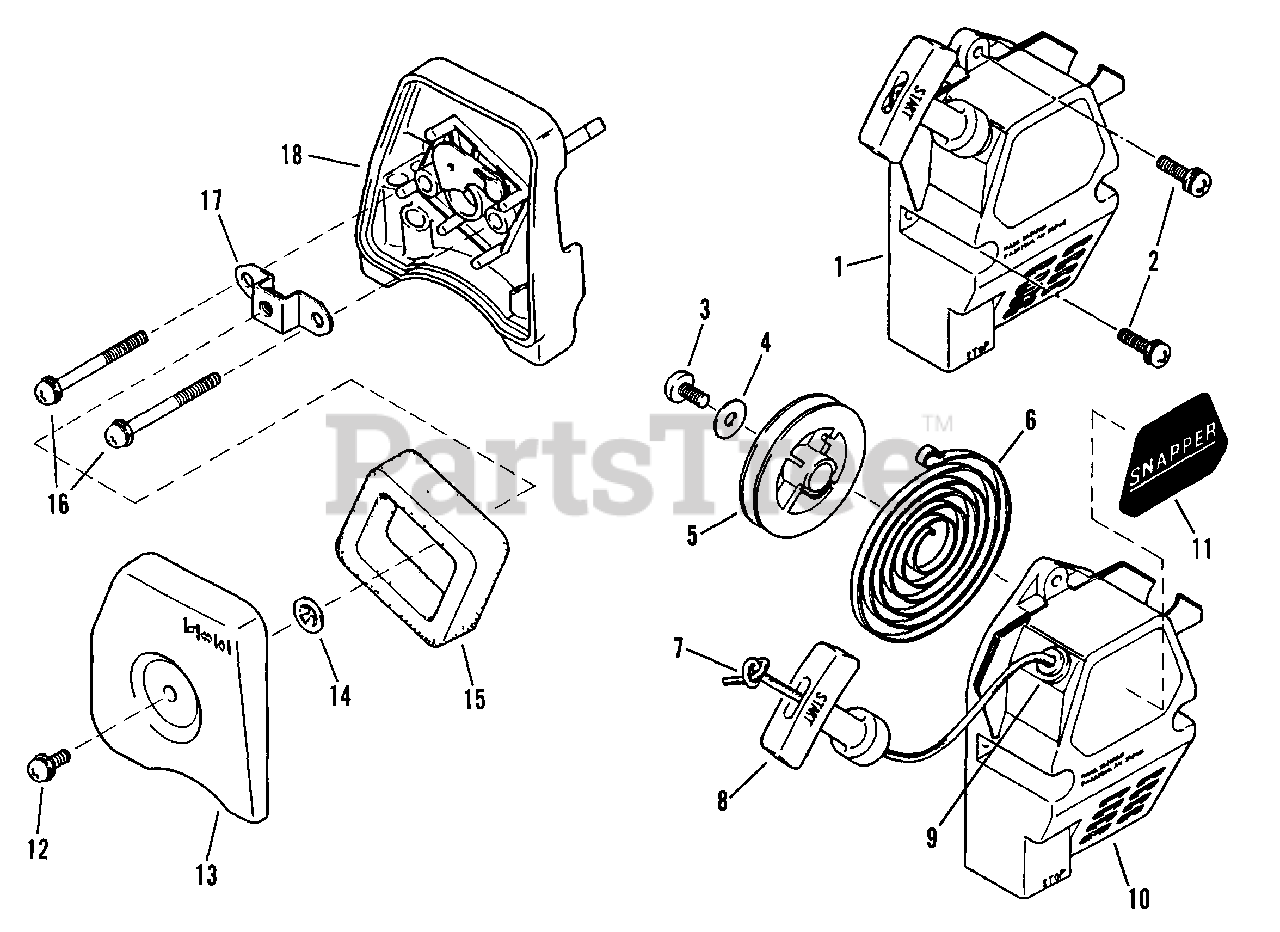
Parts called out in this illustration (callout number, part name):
1	ASSEMBLY, Recoil Starter
2	SCREW/WASHER
7	ROPE, Starter
8	KNOB, Starter
10	CASE, Starter
11	LABEL, Snapper
12	SCREW/WASHER
13	COVER, Cleaner
15	ELEMENT, Cleaner
16	SCREW/WASHER
17	BRACKET
18	CASE, Cleaner (Choke is part of this assembly)
